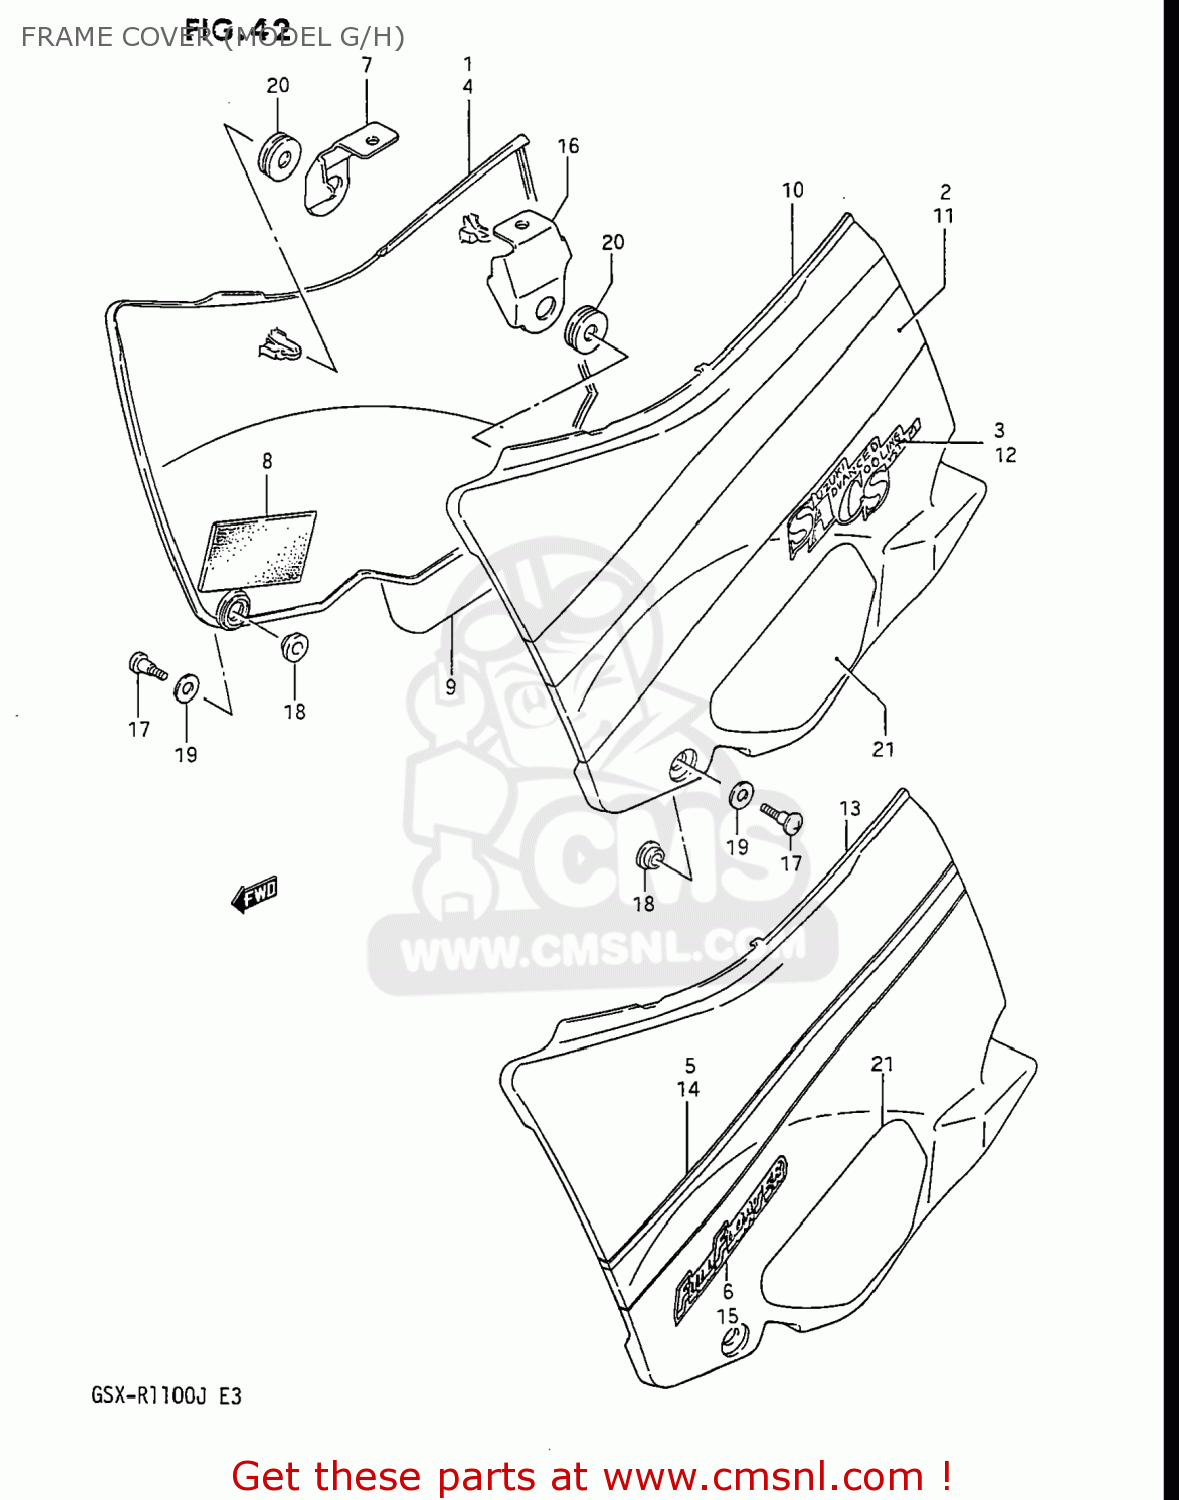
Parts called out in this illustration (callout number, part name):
1	COVER,FRAME,RIGHT
2	TAPE SET,FRAME COVER,RIGHT
3	EMBLEM
4	COVER COMP,FRAME,RIGHT
5	TAPE SET,FRAME COVER,RIGHT
6	EMBLEM
7	HOLDER,FRAME COVER,RIGHT
8	RUBBER,FRAME COVER,RIGHT
9	PROTECTOR,FRAME COVER
10	COVER,FRAME,LEFT
11	TAPE SET,FRAME COVER,LEFT
12	EMBLEM
13	COVER COMP,FRAME,LEFT
14	TAPE SET,FRAME COVER
15	EMBLEM
16	HOLDER, FRAME COVER LH
17	SCREW(6X23)
18	WASHER
19	CUSHION
20	CUSHION
21	PROTECTOR,FRAME COVER LH
